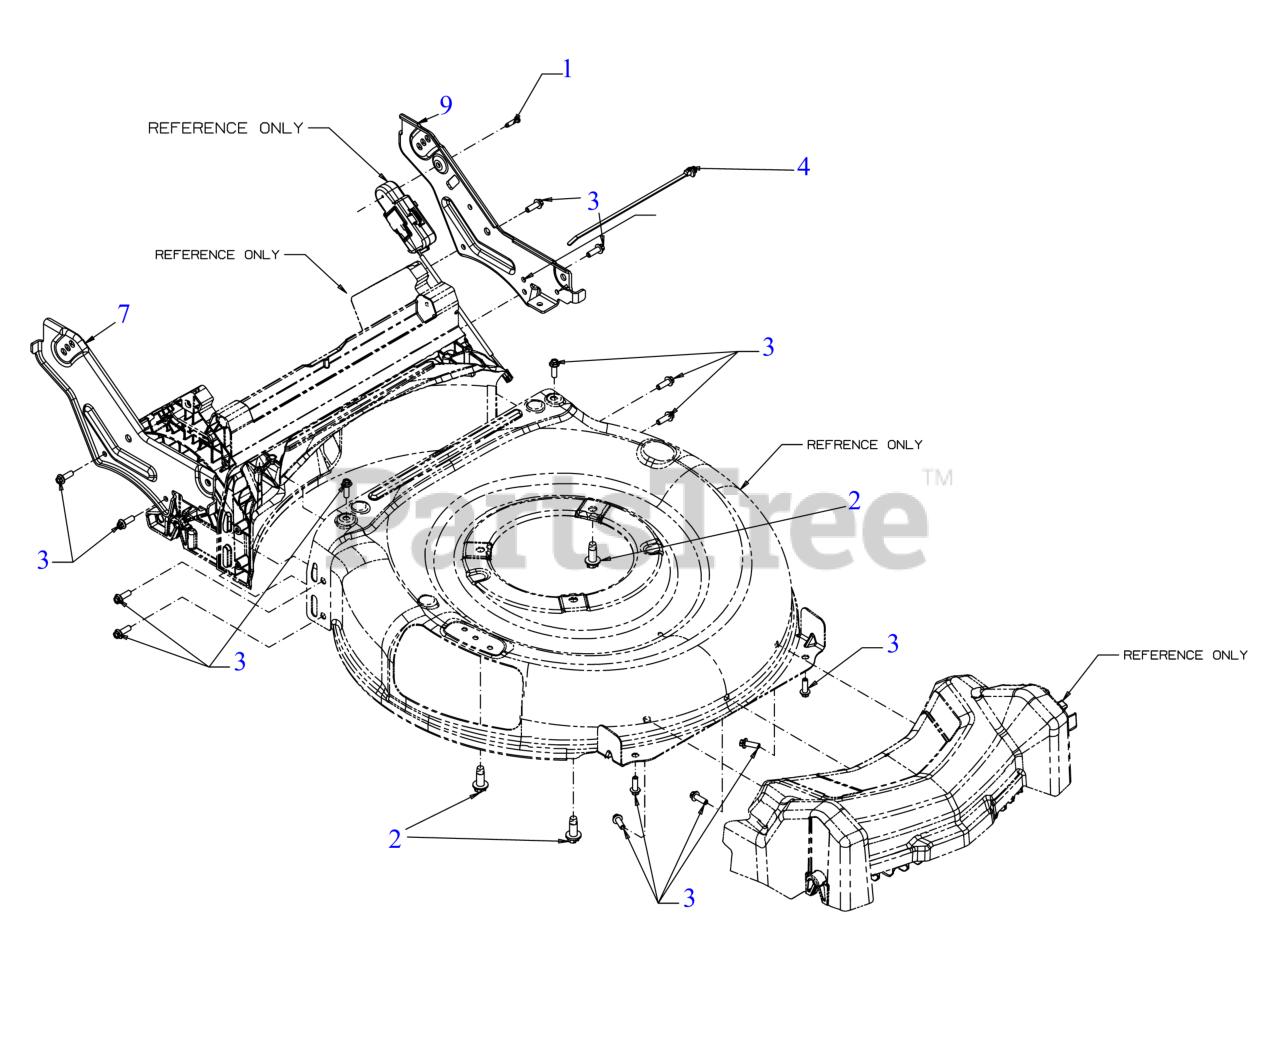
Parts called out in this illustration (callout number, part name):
1	SCREW 7-18X.75:T20
2	SCREW 3/8-16 x 1
3	SCREW 1/4 x .750
4	CABLE TIE
7	HANDLE BRACKET (RH)
9	HANDLE BRACKET (LH)
